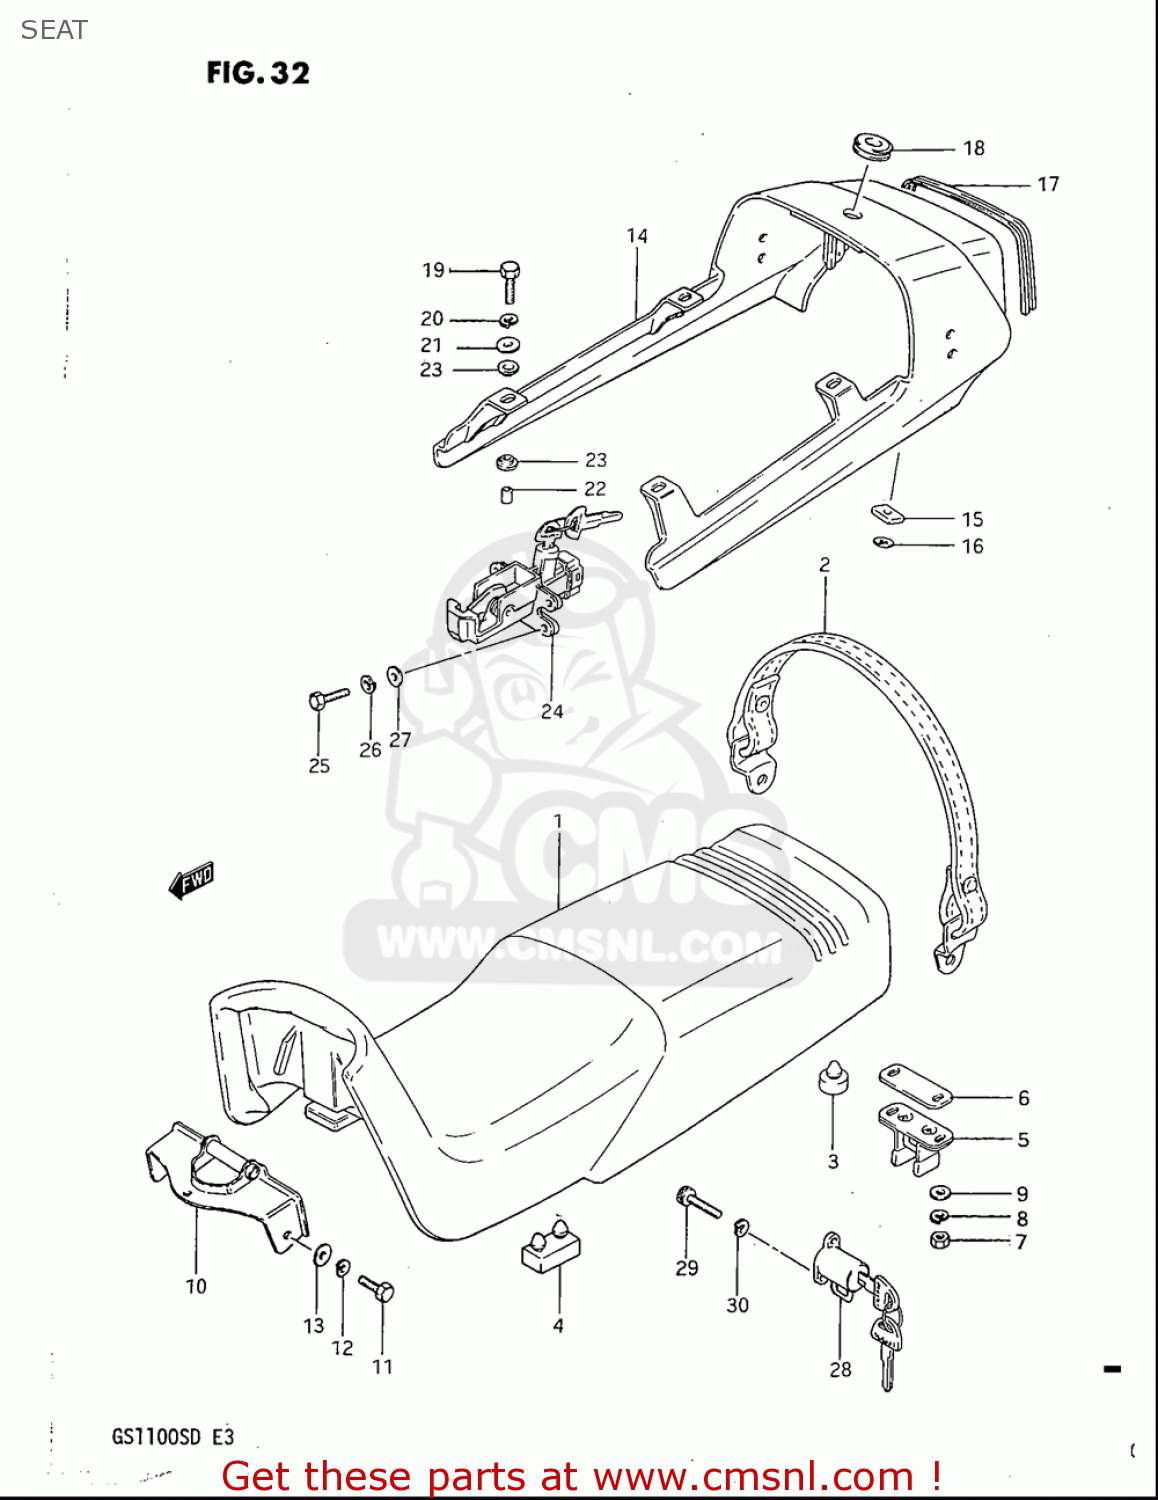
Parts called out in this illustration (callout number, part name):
1	SEAT ASSY
2	BAND,SEAT GRIP
3	CUSHION
4	CUSHION
5	STRIKER,SEAT LOCK
6	SHIM,SEAT LOCK STRIKER
7	NUT
8	WASHER,LOCK
9	WASHER
10	PLATE,SEAT HOOK FR
11	BOLT
12	WASHER,LOCK
13	WASHER
16	NUT
17	MOLE,SEAT TAIL COVER
18	GROMMET,SEAT LOCK HOLE
19	BOLT
20	WASHER,LOCK
21	WASHER(6.5X24X1.6)
22	SPACER(6.5X10X12)
23	CUSHION
24	LOCK SET,SEAT
25	BOLT
26	WASHER,LOCK
27	WASHER
28	LOCK SET,HELMET
29	BOLT,VAC.PIPE
30	WASHER,LOCK
